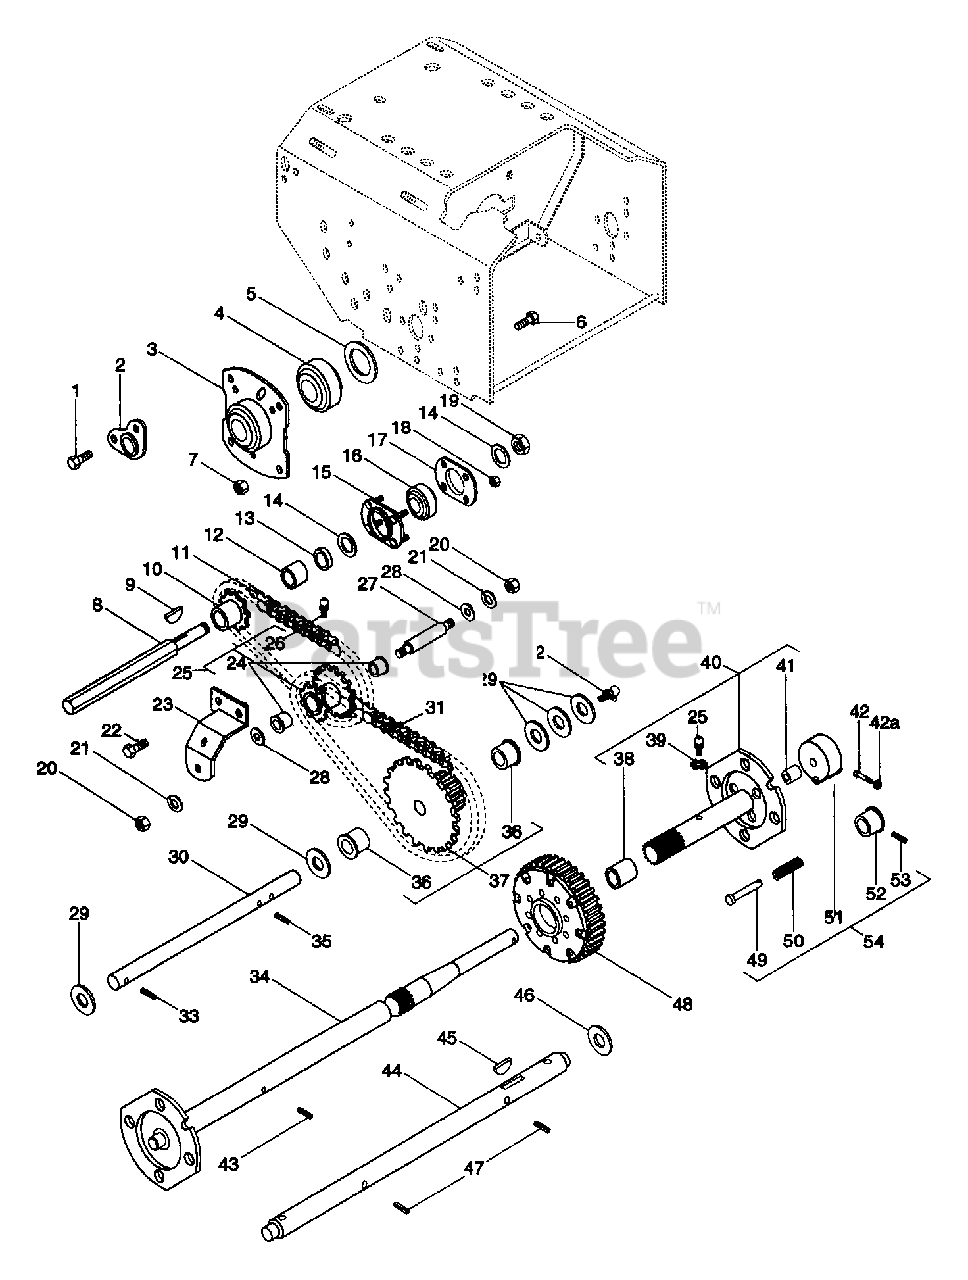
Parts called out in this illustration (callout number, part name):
1	SCR-TAP .250-20X.37 HWH PL TR
2	SUPPORT, SHAFT
3	SUPPORT, BEARING
3	BEARING RETAINER
4	BRG-BALL 1.13X2.19X.63
4	BSHG-FLG .750X1.000X.625X1.250
5	WSHR-FL-STL .755X1.375X.125
5	WSHR-FL-STL 1.140X1.718X.134
6	SCR-SLTR-SERNK .25-20X.62 PL
6	BLT-SERNK SL .25-20X.50 PL
7	NUT-LK-FLG .250-20 PL
8	HEX SHAFT
9	KEY-WDRF .125X.625X.250 SAE5
10	9 TOOTH SPROCKET
11	ROLLER CHAIN #41 22 PITCHES
11	CHAIN
12	ROLLER
13	WSHR-FL-STL .505X1.000X.062
14	WSHR-FL-STL .531X1.062X.095 PL
15	BEARING FLANGE
16	BRG-BALL .500X1.375X.437
17	BEARING FLANGE
18	NUT-LK DUAL FACE 10-24 PL
19	NUT-LK-CTR .50-20 PL
20	NUT-HEX .375-16
21	WSHR-LK .375X.130
22	SCR-TAP .250-20X.50 HXSLHDPL
23	SUPPORT, SHAFT
23	CLUTCH STOP
24	BSHG-SLV .500X.625X.500 BR
25	SPROCKET ASSEMBLY
26	FTG-LUBE .25-28X.256 YWZC
27	REDUCTION SHAFT
28	WSHR-FL-STL .382X.812X.062
29	WSHR-FL-STL .630X1.005X.062 PL
30	PINION SHAFT
31	ROLLER CHAIN #41 38 PITCHES
32	HYDRAULIC DRIVE FITTING
33	PIN-ROLL .156X1.00
34	R H AXLE
35	PIN-ROLL .125X1.00
36	BSHG-FLG .625X.750X.500X.875BR
37	PINION & SPROCKET ASSEMBLY
37	SPROCKET SERVICE ASSEMBLY
38	BSHG-SLV .750X.814X .750 BRZ
39	WSHR-LK .250X.047 LT PL
40	L.H. AXLE ASSEMBLY
40	L.H.AXLE ASSEMBLY
41	BSHG-SLV .562X.625X.625 BRZ
42	BLT-HEX .25-20X2.0 GR8 PL
42A	NUT-JAM-NYL .250-20 W/INSRT
43	PIN-ROLL .188X1.50
44	AXLE SHAFT
45	KEY-WDRF .25X.750X.313 SAE91
46	WSHR-FL-STL .755X1.375X.125
47	PIN-ROLL .188X1.25
48	DIFFERENTIAL ASSEMBLY
49	PIN
50	SG-COMP .028X.34X1.062 WLD75
51	LOCKOUT HUB
52	KNOB
53	PIN-ROLL .093X1.00
54	LOCKOUT HUB ASSEMBLY
